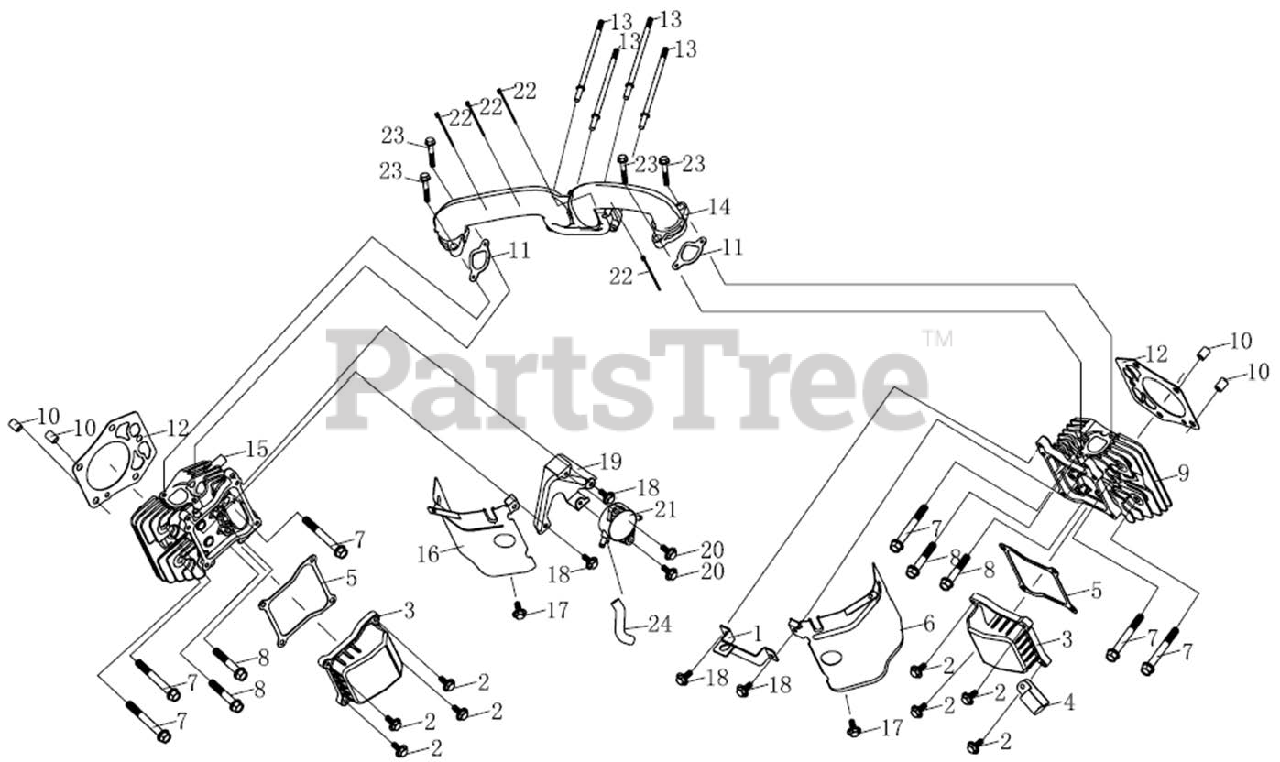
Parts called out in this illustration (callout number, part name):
1	LIFTING EYE
2	HEXAGON BOLT WITH FLANGE
3	CYLINDER HEAD COVER ASSY
4	CABLE CLEAT
5	GASKET FOR CYLINDER HEAD COVER
6	AIR DEFLECTOR
7	HEXAGON BOLT WITH FLANGE
8	HEXAGON BOLT WITH FLANGE
9	CYLINDER HEAD
10	LOCATION PIN
11	CARBURETOR GASKET
12	GASKET FOR CYLINDER HEAD
14	INTAKE PIPE
15	CYLINDER HEAD (WITH PORTS)
16	AIR DEFLECTOR
17	BOLT, FLANGE
18	BOLT, FLANGE
19	GASOLINE PUMP BRACKET
20	BOLT, FLANGE
21	GASOLINE PUMP
23	BOLT, FLANGE
24	BREATHER TUBE
